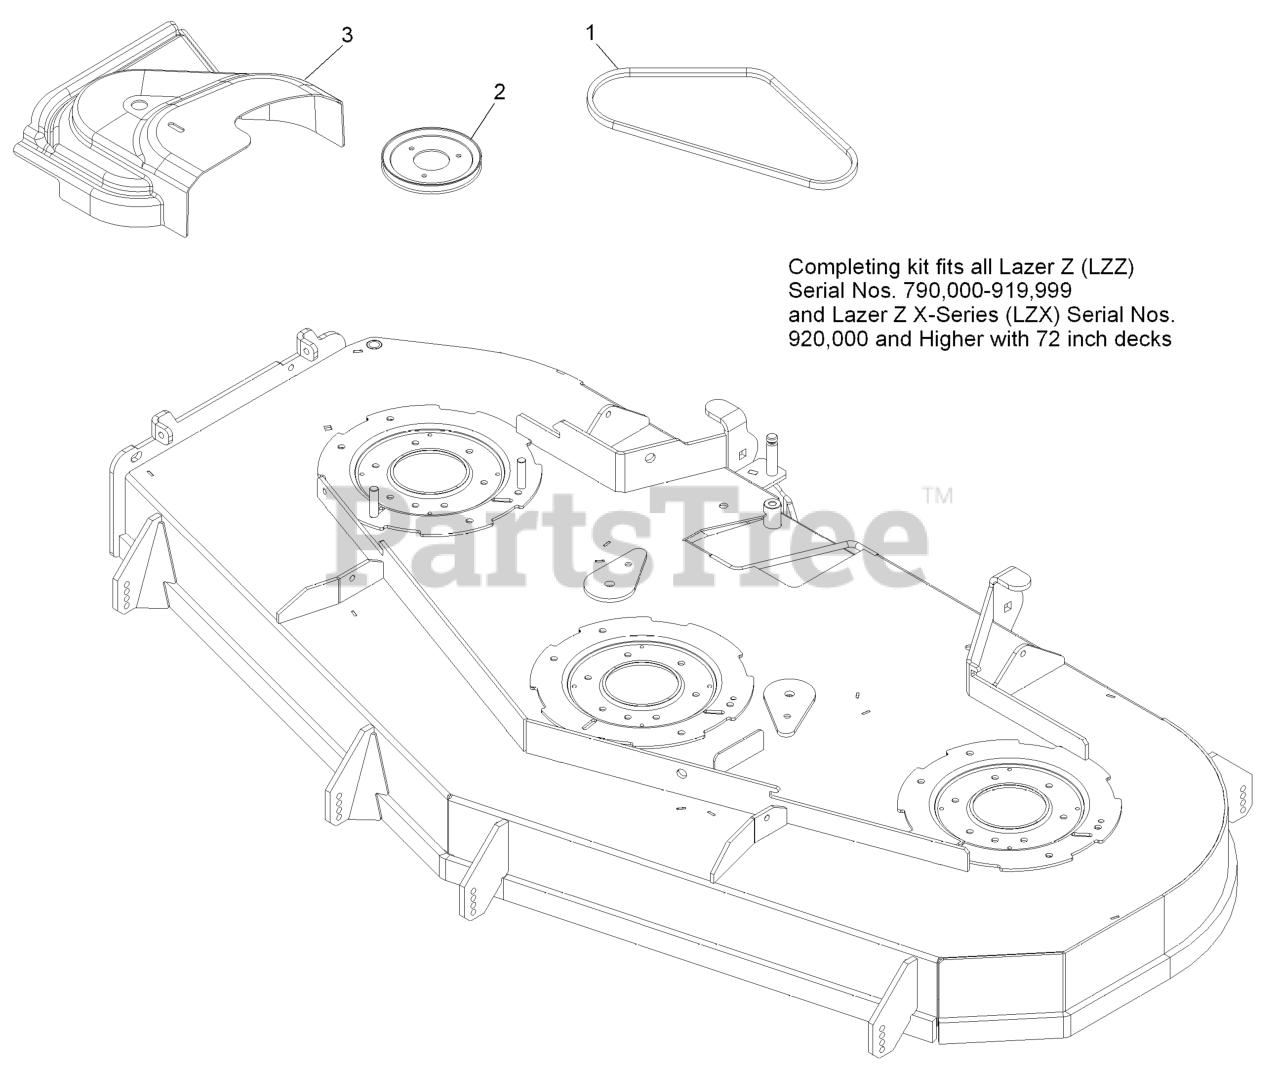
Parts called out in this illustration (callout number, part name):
1	BELT, BLOWER DRIVE 72
2	SHEAVE,DRIVE LZUV 726
3	COVER,BELT UV 72
